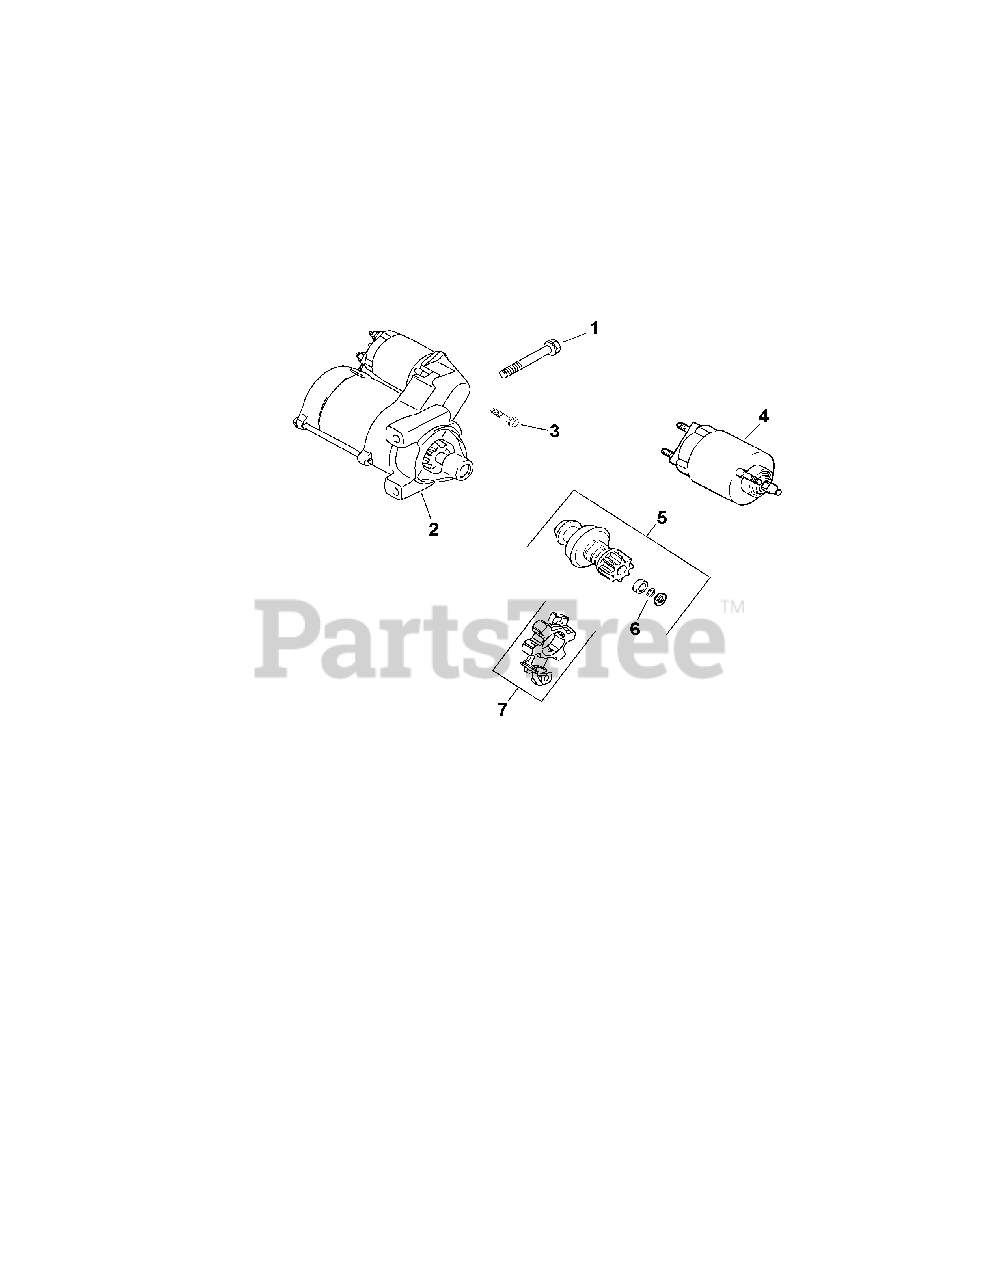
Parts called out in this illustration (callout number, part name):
1	Screw, hex. flange M8x1.25x80 (2)
2	Starter, solenoid assembly (Includes 3-7)
3	Screw, external torx hd. (3)
4	Kit, solenoid (Includes 4)
5	Kit, starter pinion (Includes 6)
